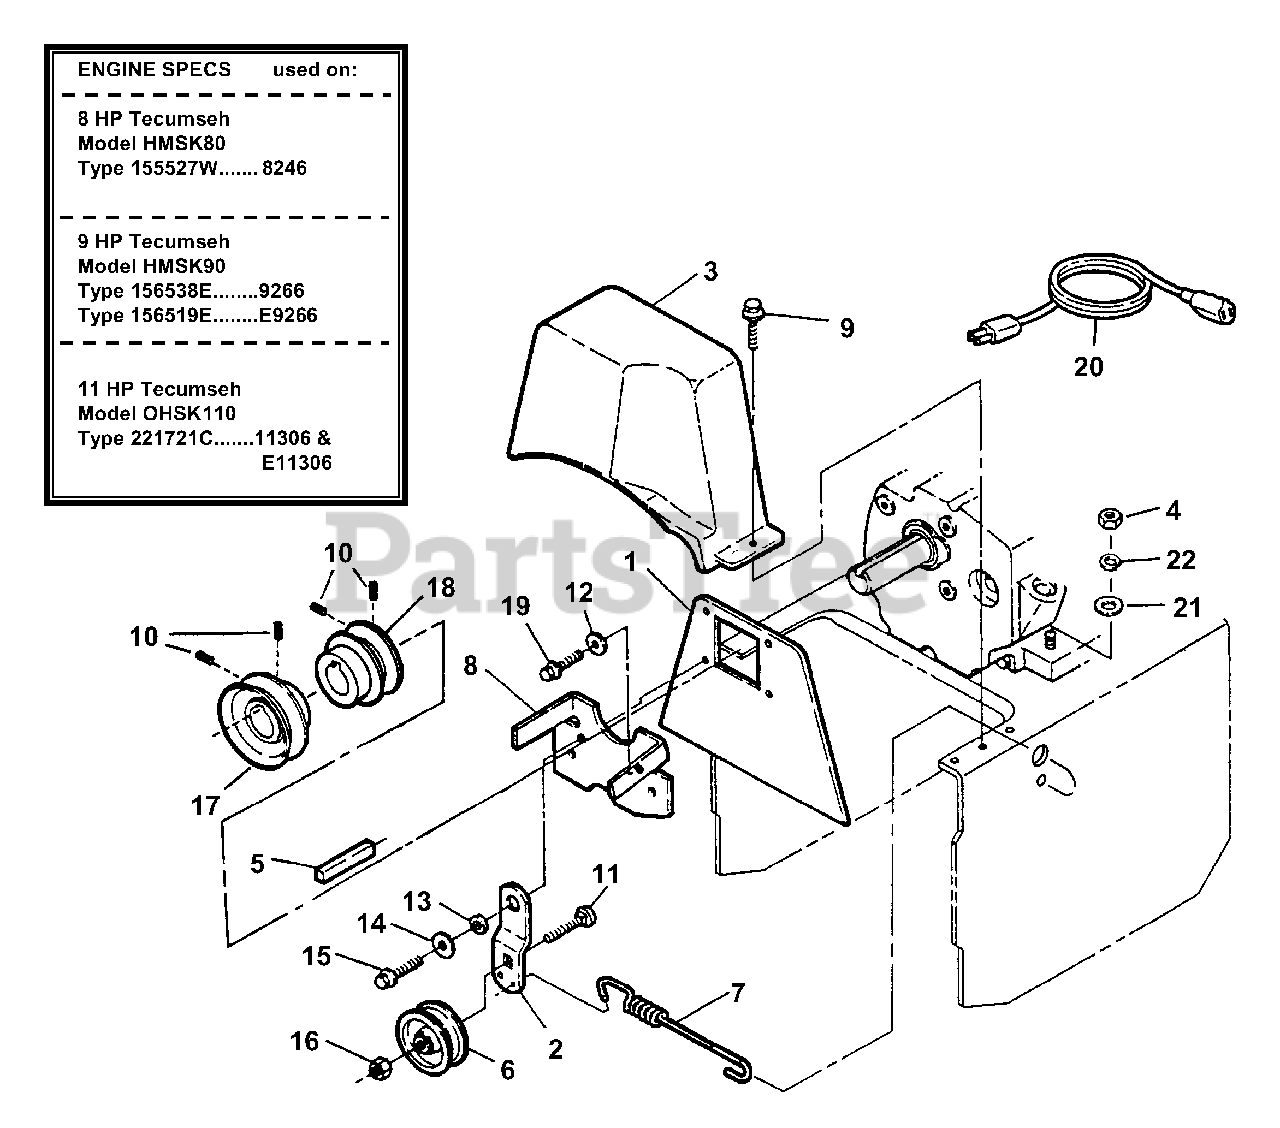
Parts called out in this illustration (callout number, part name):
1	GUARD, Engine
2	ARM, Idler
3	COVER, Belt
4	NUT, 5/16-18 Hex, Grade B or 5
5	KEY, 1/4 x 2" Square
6	IDLER
7	SPRING, Idler
8	FINGER, Belt
9	SCREW, 1/4-20 x 1/2" Hex Washer Self-Tap
10	SCREW, 5/16-18 x 5/16" Socket Head Set
11	BOLT, 3/8-16 x 1-1/2" Square Neck Carriage, Grade 2
12	WASHER, 5/16 Flat
13	SPACER
14	WASHER, 3/8" Flat
15	SCREW, 5/16-24 x 7/8" Hex Head Cap, Grade 5
16	NUT, 3/8-16 Hex Top Lock
17	PULLEY, Blower
18	PULLEY, Traction
19	SCREW, 5/16-24 x 3/4" Hex Head Cap, Grade 5
20	CORD, 10' Extension
21	WASHER, 5/16 Flat
22	WASHER, 5/16 Split Lock
